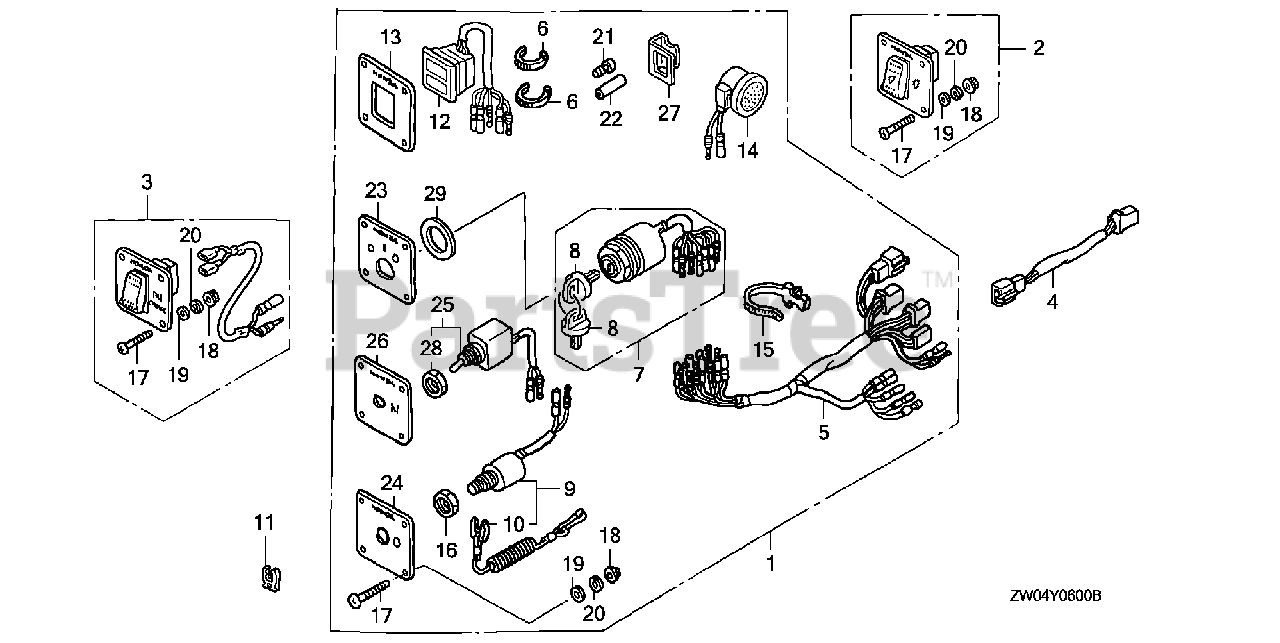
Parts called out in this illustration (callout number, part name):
1	PANEL KIT, CONTROL (B)
2	SWITCH KIT, LIGHT
3	SWITCH KIT, SOLENOID
4	SUB-HARNESS ASSY., POWER
5	HARNESS ASSY., SWITCH PANEL
6	TIE, CABLE
7	SWITCH ASSY., COMBINATION
8	KEY ASSY., COMBINATION SWITCH
9	SWITCH ASSY., EMERGENCY STOP
10	WIRE, EMERGENCY
11	CLIP, EMERGENCY LOCK
12	LAMP ASSY., INDICATOR
13	PANEL, INDICATOR
14	BUZZER, WARNING
15	NUT, HEX. (16MM)
16	BAND, WIRE HARNESS (WHITE)
17	SCREW, PAN (5X40)
18	NUT, FLANGE (5MM)
19	WASHER, PLAIN (5MM)
20	WASHER, SPRING (5MM)
21	PLUG, CONNECTOR (INNER)
22	PLUG, CONNECTOR (OUTER)
23	PANEL, SWITCH
24	PANEL, EMERGENCY STOP SWITCH
25	SWITCH ASSY., SOLENOID
26	PANEL, SOLENOID
27	BRACKET, BUZZER
28	NUT, HEX. (12MM)
29	WASHER, PLAIN
